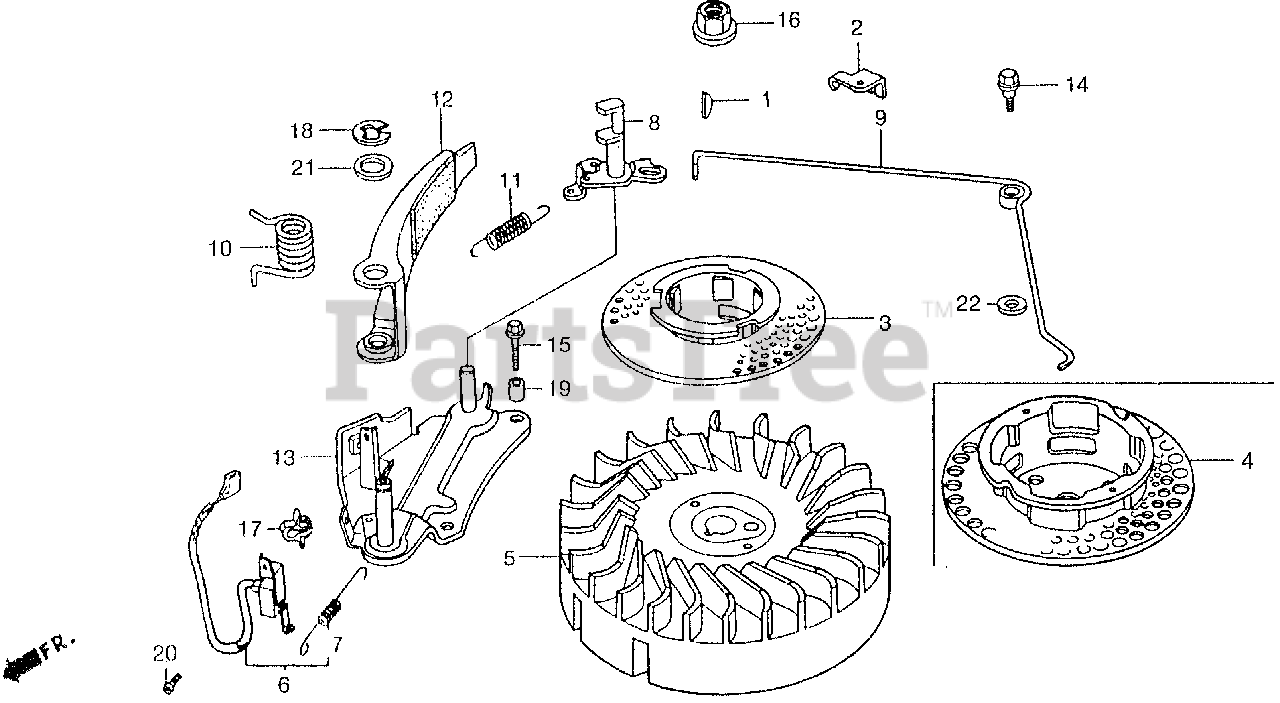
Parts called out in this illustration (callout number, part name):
1	KEY, SPECIAL WOODRUFF (25X18)
2	HOLDER, CABLE
3	PULLEY, STARTER
4	PULLEY, STARTER
5	FLYWHEEL
6	SWITCH ASSY., ENGINE STOP
7	SPRING, SWITCH CONTROL
8	CAM, BRAKE
9	ROD, THROTTLE RETURN
10	SPRING, BRAKE
11	SPRING, BRAKE RETURN
12	BRAKE
13	BASE, BRAKE
14	BOLT, FLANGE (6MM)
15	BOLT, FLANGE (6X22)
16	NUT, SPECIAL (14MM)
17	CLIP, WIRE HARNESS
18	E-RING (10MM)
19	PIN, DOWEL (8X9)
20	SCREW, PAN (4X8)
21	WASHER, PLAIN (12MM)
22	WASHER, DRUM STOPPER
